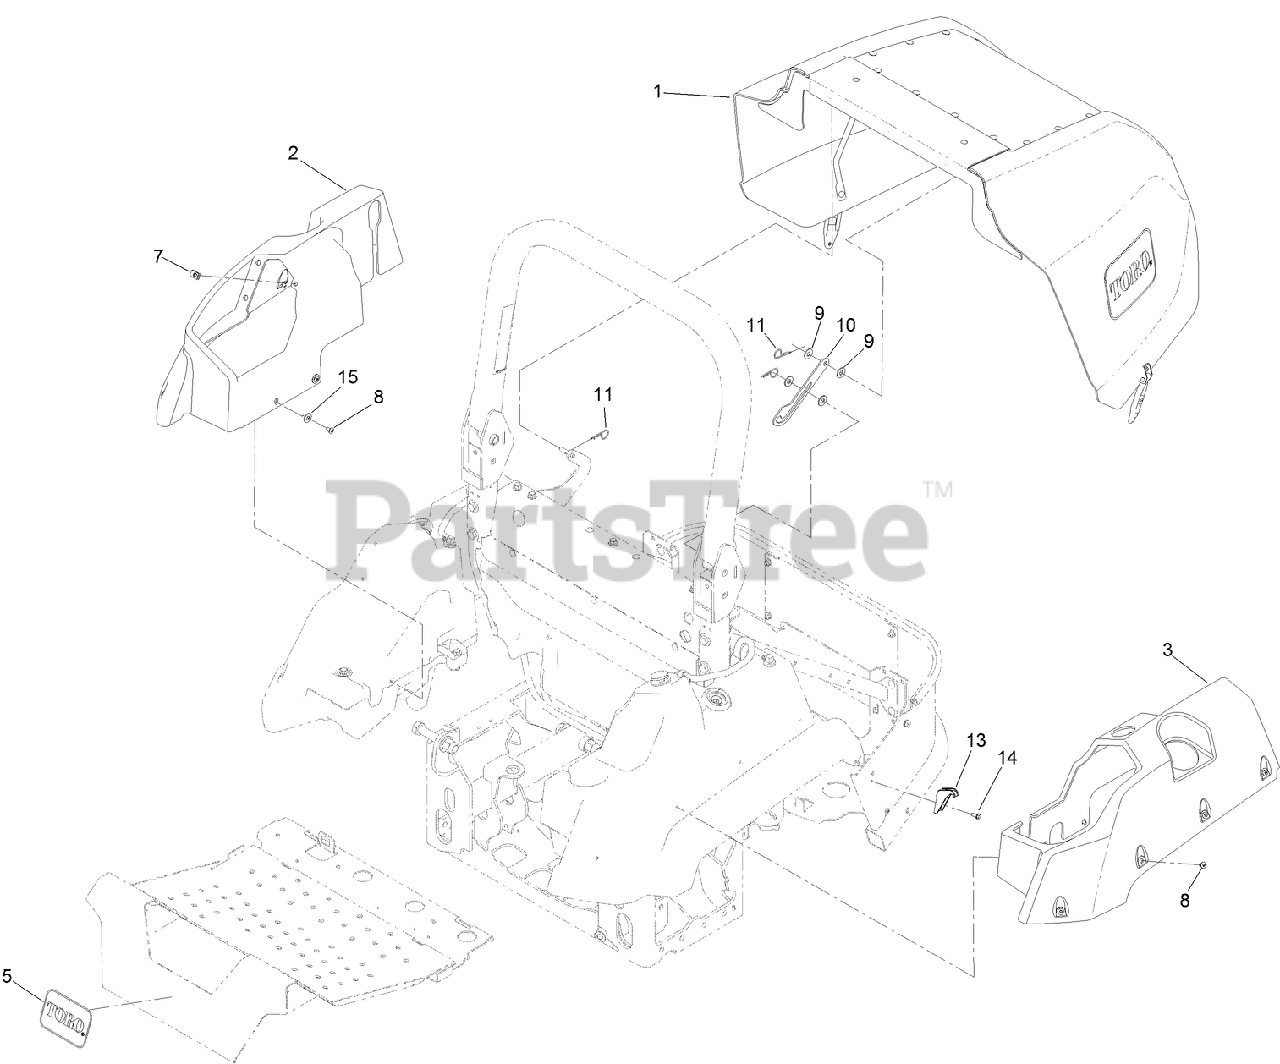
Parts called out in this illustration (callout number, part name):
1	HOOD ASM
2	COVER-TANK, RH
3	COVER-TANK, LH
5	DECAL
8	SCREW-TORX
9	WASHER-FLAT
10	PROP-HOOD
11	PIN-COTTER, HAIR
13	LATCH-CATCH
14	SCREW-HWH
15	WASHER-FLAT
